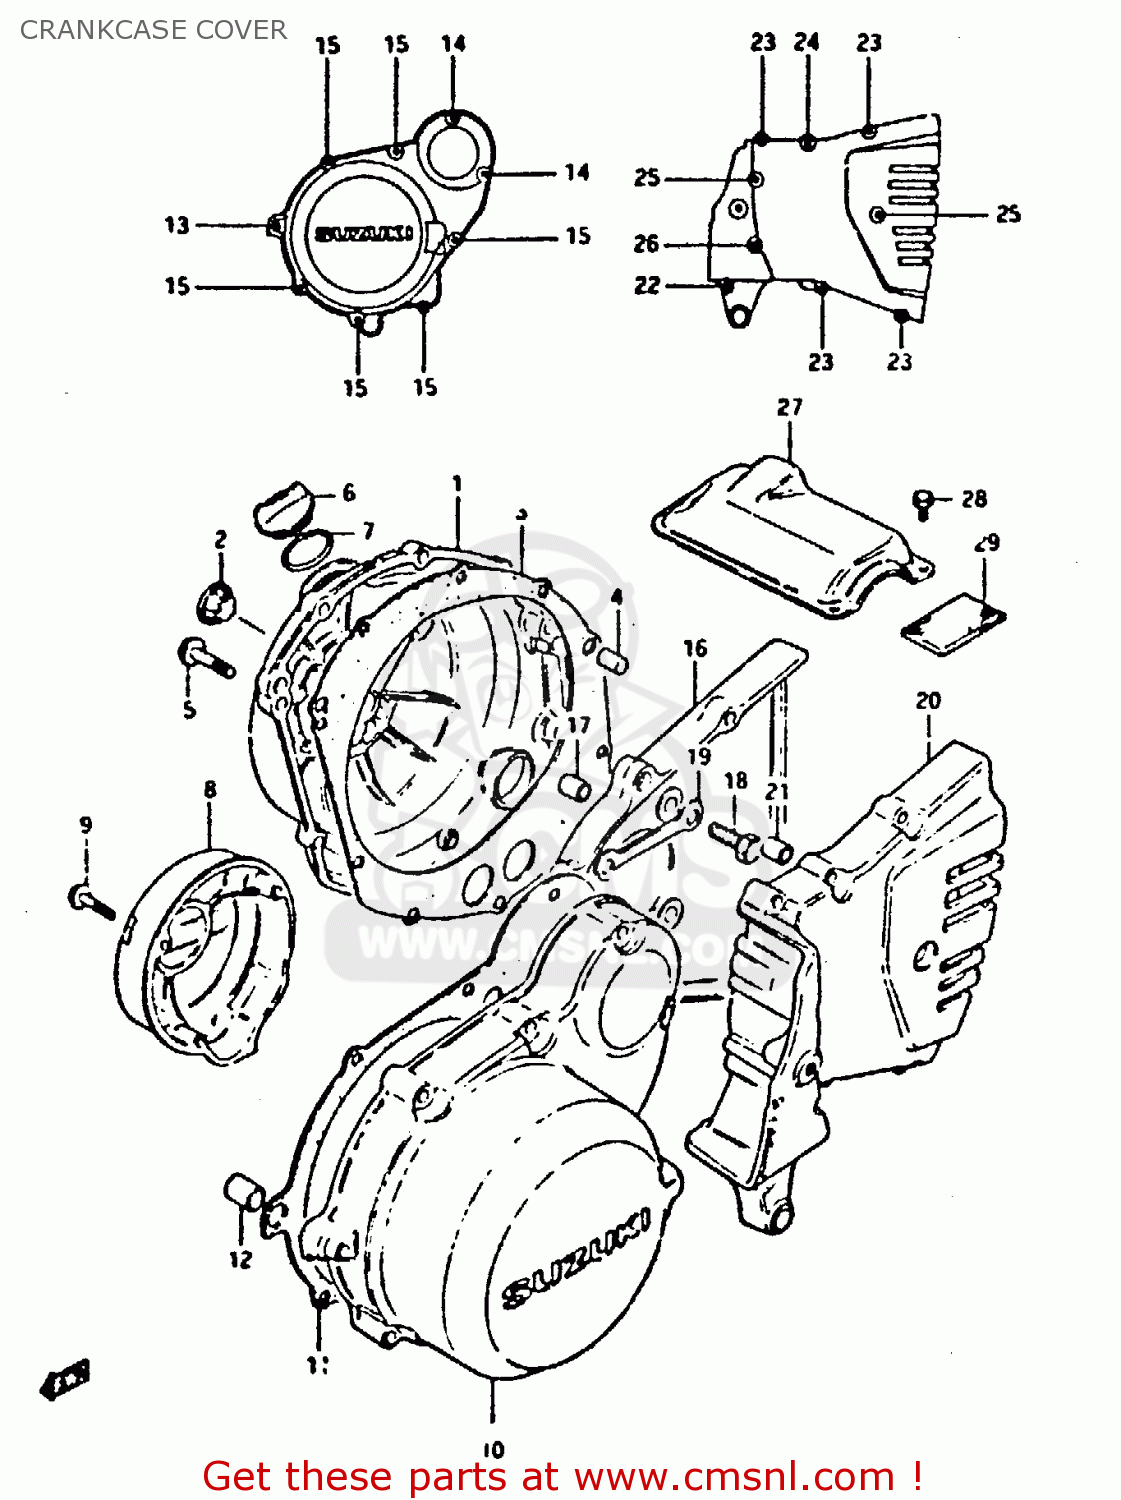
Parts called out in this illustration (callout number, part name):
1	COVER,CLUTCH
2	LENS,OIL LEVEL CHECK
3	GASKET,CLUTCH COVER
4	PIN(8X23)
5	BOLT (6X30)
6	PLUG
7	O-RING
8	COVER,CONTACT BREAKER
9	BOLT (5X30)
10	COVER,MAGNETO
11	GASKET,MAGNETO COVER
12	PIN
13	BOLT
14	BOLT (6X40)
15	BOLT (6X35)
16	COVER,SPROCKET
17	PIN
18	BOLT
19	WASHER
20	COVER,ENGINE SPROCKET,OUTER
21	PIN
22	BOLT
23	BOLT (6X30)
24	BOLT (6X35)
25	BOLT
26	BOLT (6X70)
27	COVER
28	BOLT
29	DAMPER,STARTER MOTOR CLUTCH
